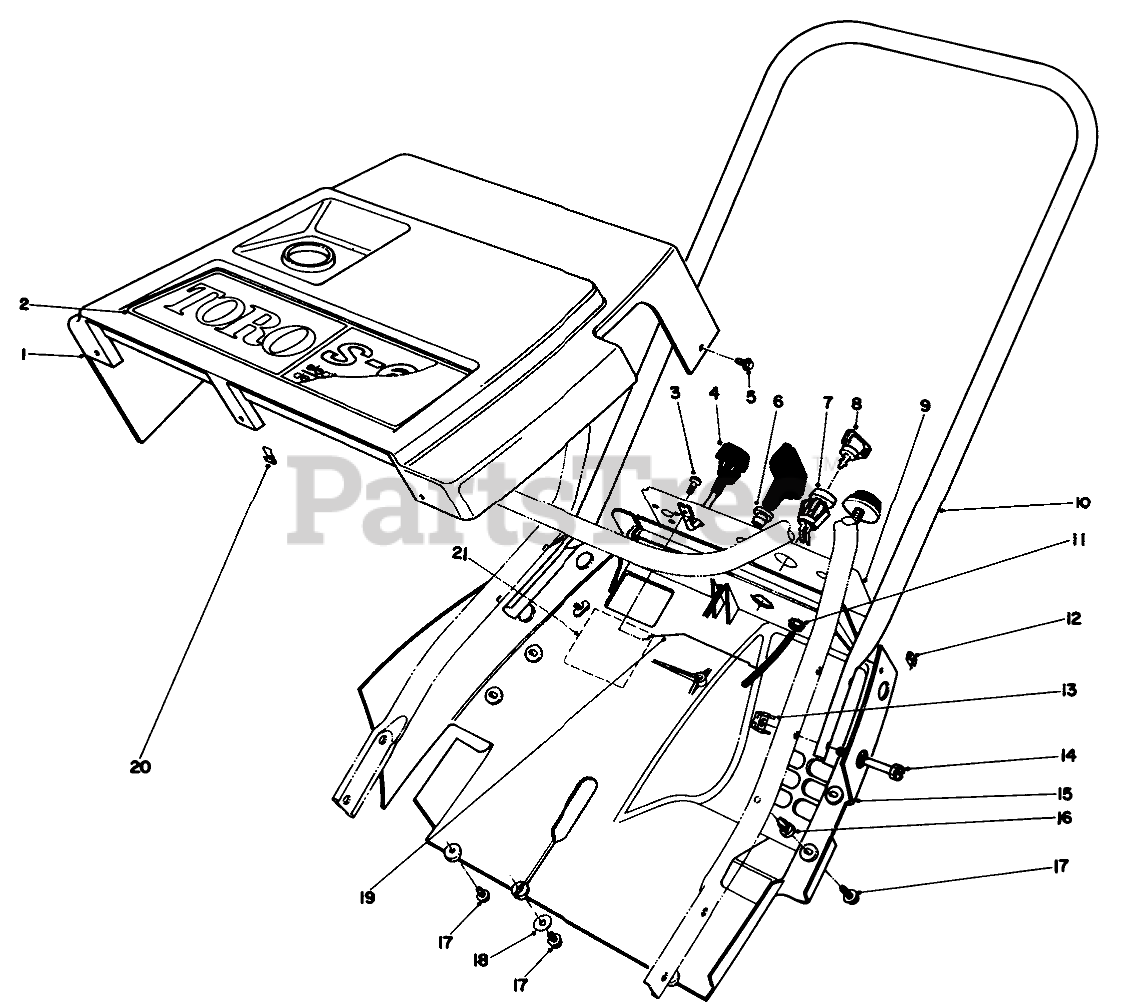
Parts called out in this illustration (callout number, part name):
1	Shroud-Upper
2	TORO DECAL
3	SCREW-PLASTITE
4	CHOKE CONTROL ASM
5	SCREW-HWHTF
6	GUIDE-ROPE, STARTER
7	SWITCH
8	KEY-IGNITION
9	CONTROL PANEL DECAL
10	UPPER HANDLE ASM
11	NUT-KEPS
13	TINNERMAN NUT
14	SCREW-HEX HD SLOT
15	LOWER SHROUD
16	Nut-Push
17	SCREW-HWHTF
18	WASHER-FLAT
19	CONTROL WIRE
20	NUT "U"
21	DECAL - CSA
